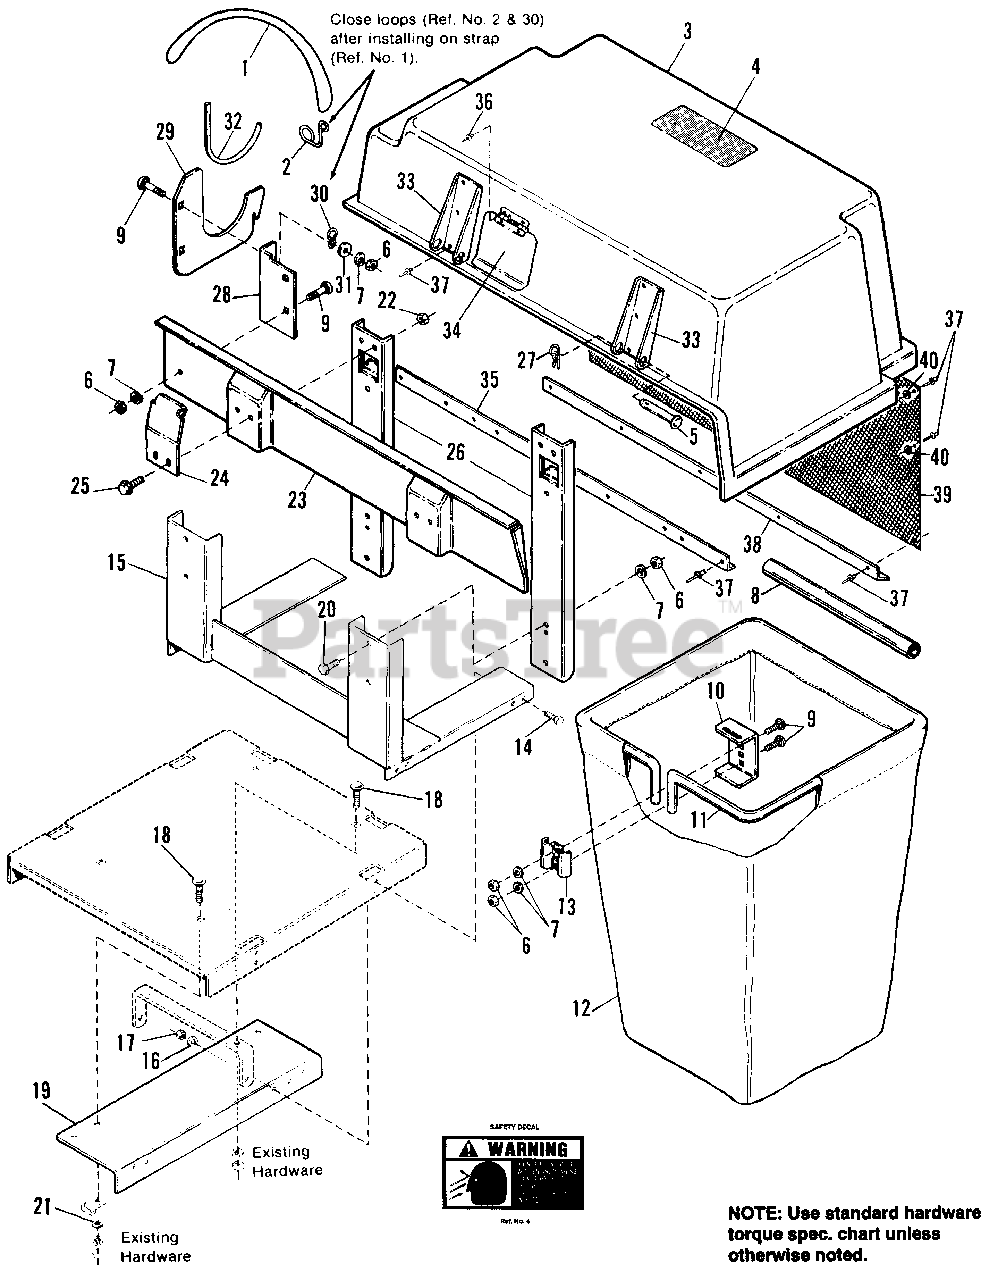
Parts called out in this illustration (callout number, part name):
2	HOOK, Strap
3	COVER ASSY.
4	DECAL, Warning
6	NUT, Hex, 5/16-18
7	LOCKWASHER, 5/16
9	BOLT, Carriage, 5/16-18 x 7/8
14	CAPSCREW, Hex, 1/4-20 x 3/4
15	BRACKET ASSY.
16	LOCKWASHER, 1/4
17	NUT, Hex, 1/4-20
18	BOLT, Carriage, 5/16-18 x 1
19	ANGLE, Support
20	CAPSCREW, Hex, 5/16-18 x 7/8
21	WASHER, 5/16
22	NUT, Hex, Lock, 5/16-18
23	PLATE, Support, Cover
24	PLATE, Hinge
25	SCREW, Hex, Flange Whizlock, 5/16-18 x 3/4
26	BRACE, Upper
27	CLIP, Hairpin
28	MOUNT, Saddle Bracket
29	BRACKET, Saddle
31	WASHER, Plain
33	BRACKET, Hinge
34	DOOR & HINGE, Inspection
35	BRACKET, Cover, Front
38	BRACKET, Cover, Rear
40	WASHER, Rivet
